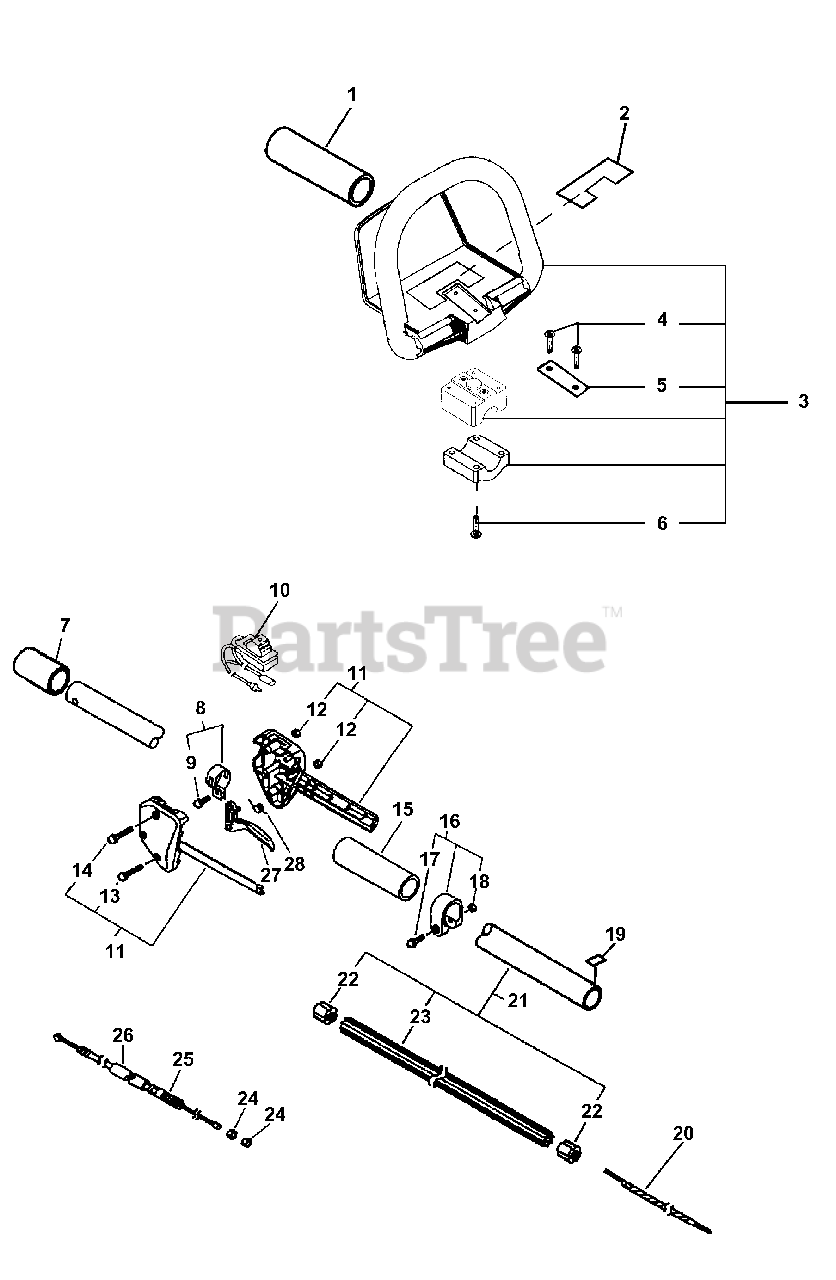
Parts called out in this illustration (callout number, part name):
1	COLLAR, MAIN PIPE
2	LABEL - WARNING
3	HANDLE ASSY - FRONT
4	SCREW - 5X30
6	SCREW - 5
7	COLLAR
8	CLAMP KIT
9	SCREW - 5X14
10	IGNITION SWITCH ASSY
11	THROTTLE BRACKET SET
13	SCREW - 5X25
14	SCREW - 5X35
15	GRIP, HANDLE - REAR
16	CLAMP
17	SCREW - 5X28
19	LABEL - ALIGNMENT
20	DRIVESHAFT - FLEXIBLE
21	MAIN PIPE ASSY
23	LINER - FLEXIBLE
25	CABLE, THROTTLE
26	TUBE, PROTECTIVE - CORRUGATED
27	TRIGGER, THROTTLE
28	SPRING, TRIGGER
